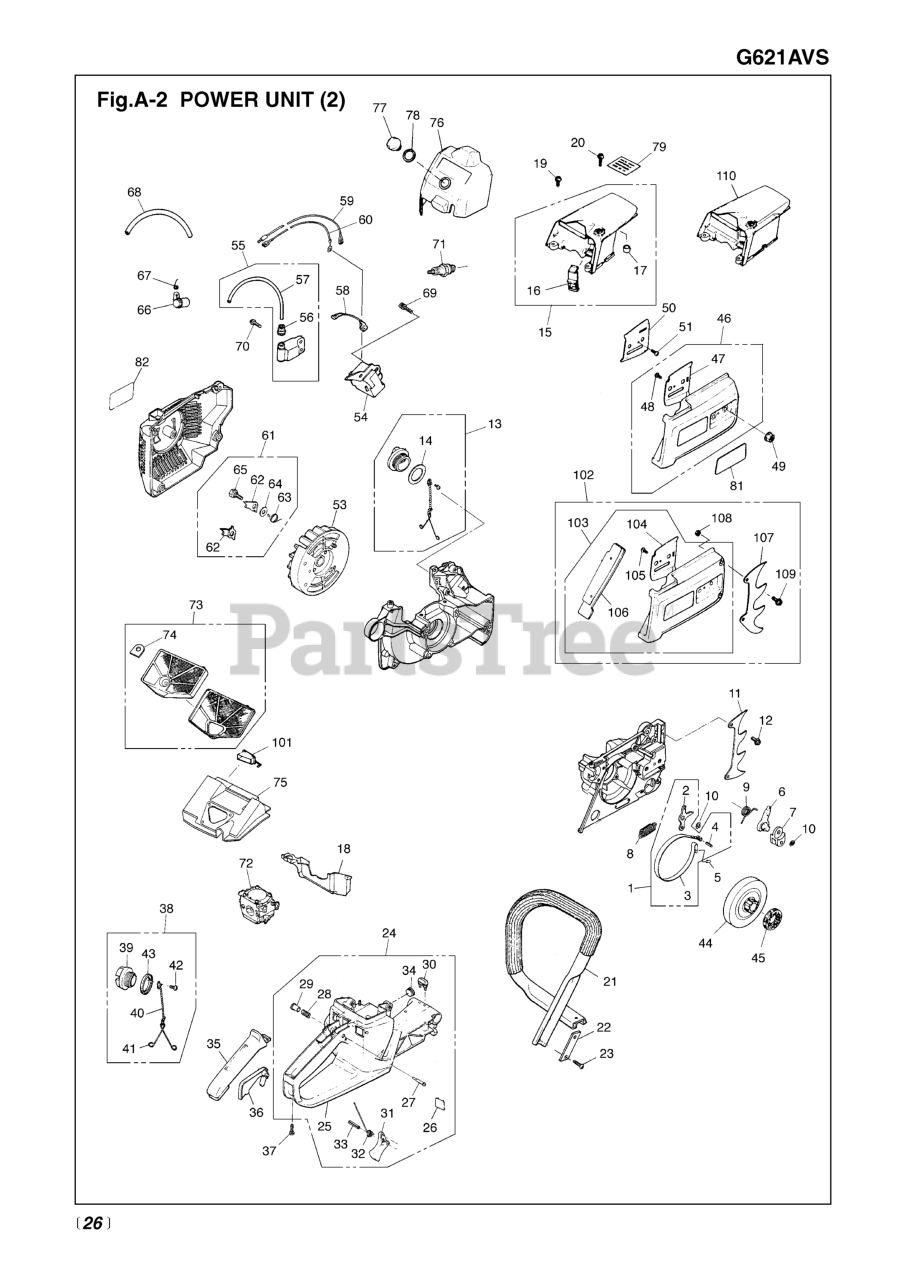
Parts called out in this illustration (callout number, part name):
1	BAND COMP
2	BAND
3	ARM
5	PIN
6	LEVER, BRAKE (RPLS.3356-24210)
7	STOPPER (REPLACES 2622-24500)
8	SPRING COMP
9	SPRING
10	RING, SNAP, M6
11	BUMPER SPIKE
12	SCREW
13	CAP ASSEMBLY
14	GASKET
15	COVER COMP.
16	CAP
17	GROMMET (RPLS-31151)
18	SEAL, CYLINDER
19	SCREW,M5 X 14 (RPLS 1400-15510
20	SCREW, M5X20 (RPLS.1400-75510)
21	HANDLE L
22	PLATE (RPLS 2616-32180)
23	SCREW (RPLS. 2671-32110)
24	R HANDLE ASSY (RPLS -33002)
25	HANDLE (RPLS -33104)
27	STOPPER
29	KNOB
30	DAMPER (REPLACES 3356-33281)
31	LEVER
32	SPRING
34	DAMPER (RPLS -33411)
35	GRIP COVER
36	ARM (REPLACES 3356-33352)
37	SCREW
38	TANK CAP ASSY
39	CAP-TANK
42	SCREW, M4 x 10
43	GASKET
44	DRUM, CLUTCH
45	SPROCKET RIM, 3/8, 7-TOOTH
46	COVER, CHAIN (RPLS. -53002)
47	PLATE (OUT)
48	SCREW, M4 x 10
49	NUT
50	PLATE (IN)
51	SCREW, M4 x 10
53	ROTOR (RPLS -71110)
54	COIL-SO (REPLACES 2616-71210)
55	COIL, IGNITION
56	CAP
58	CORD
59	CORD
61	ROTOR COMP.
62	RATCHET
63	SPRING (REPLACES -71130)
65	BOLT
66	CAP, PLUG
67	SPRING PLUG (RPLS 3310-71320)
69	BOLT
70	SCREW (REPLACES -30414)
71	SPARK PLUG
72	CARBURETOR (HDA-212-1)
73	CLEANER, AIR (RPLS 3356-98200)
74	PLATE
75	SILENCER
76	COVER (RPLS -83300)
78	GASKET, KNOB
101	CAP, SILENCER
102	DOUBLE SPIKE KIT
103	CHAIN COVER
104	PLATE (OUT)
105	SCREW, M4 x 10
106	PROCTECTOR
107	BUMPER SPIKE
108	NUT (B)
109	SCREW (REPLACES 2616-24320)
110	COVER (G621AVS)
